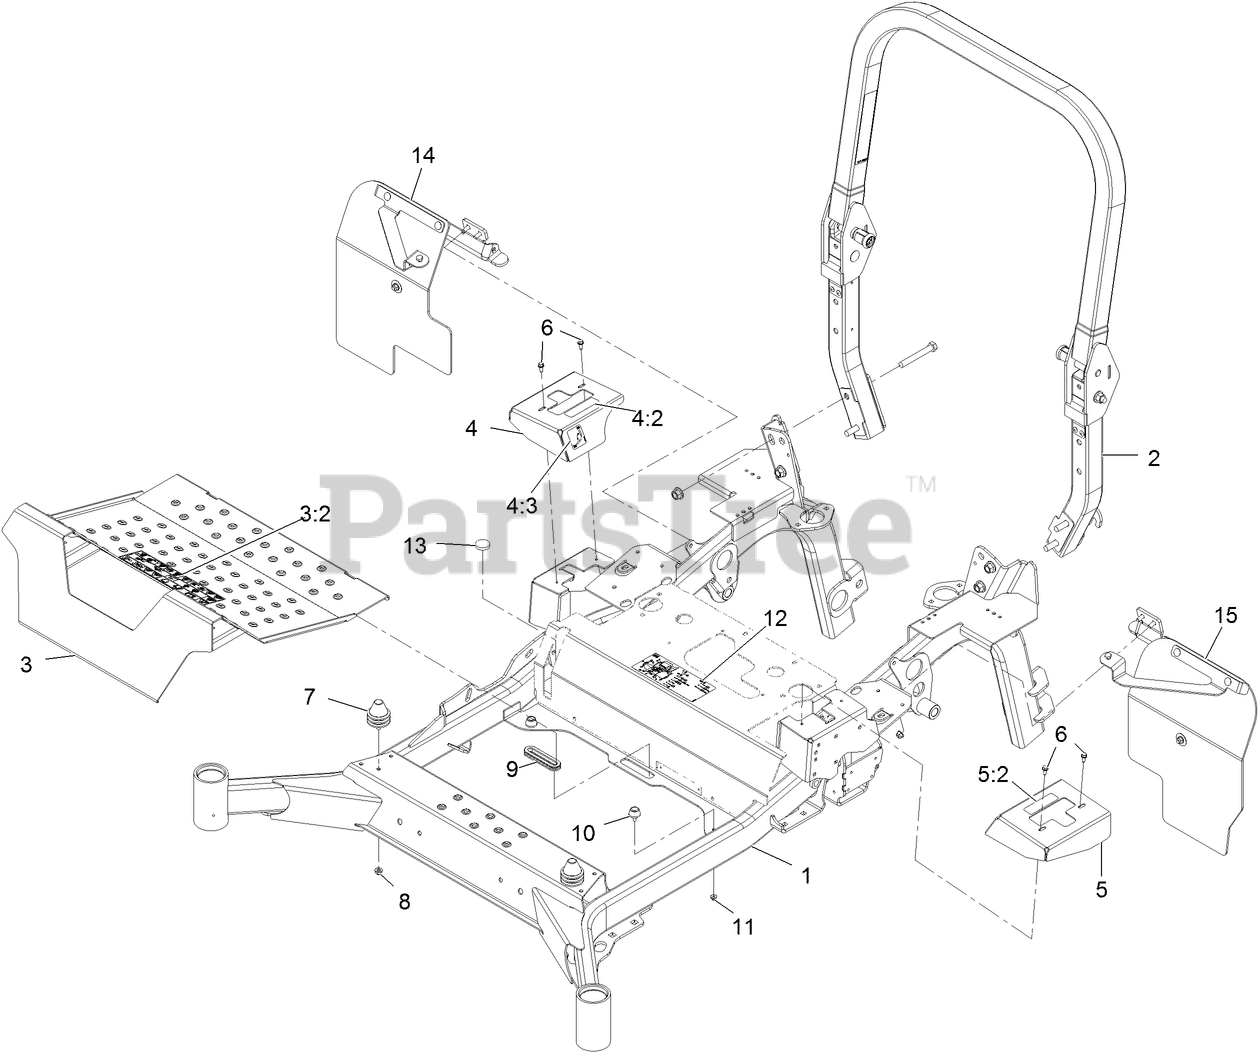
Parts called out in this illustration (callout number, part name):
1	FRAME-MAIN
2	ROPS ASM
2	ASM, ROPS-7500D DIESEL
3	PAN-FLOOR
3:2	DECAL-DANGER
4	COVER-MOTION CONTROL, RH
4:2	DECAL-CONTROL, MOTION
4:3	DECAL-PARK BRAKE, CE
5	COVER-MOTION CONTROL, LH
5:2	DECAL-CONTROL, MOTION
6	SCREW-HWH
7	ISOLATOR
8	NUT-HF, NI
9	GROMMET-RUBBER
10	BUMPER-RUBBER
11	NUT-HF
12	DECAL-SERVICE AID
13	BUMPER-PUSH-IN, RUBBER
14	ASM, RH MUD FLAP
15	ASM, LH MUD FLAP
